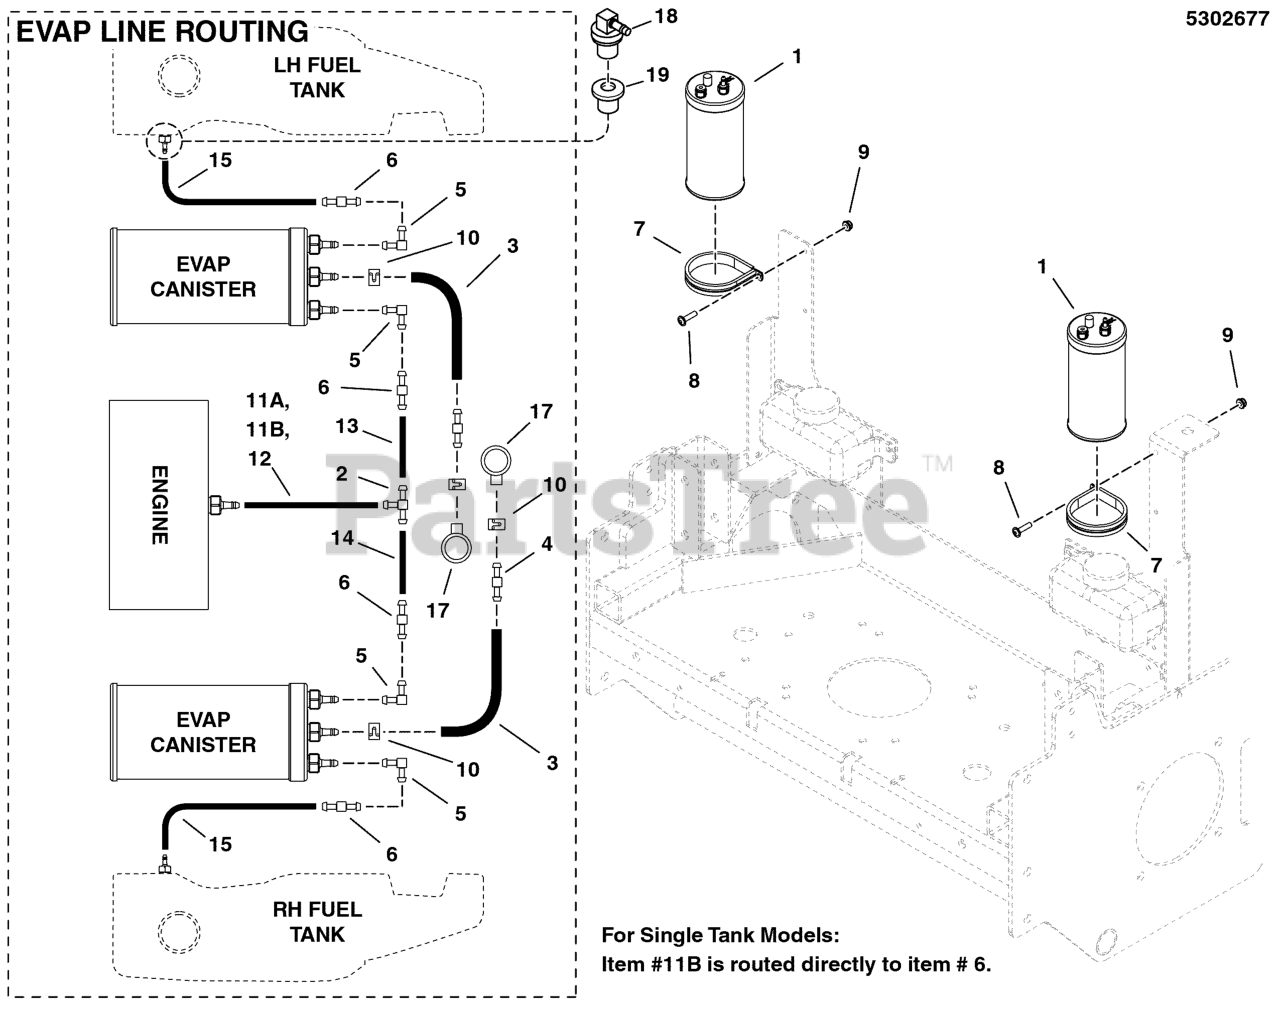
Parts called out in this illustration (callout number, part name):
1	CNSTR, CARB, 6 GAL
2	FITTING, 3/16" TEE, BARB TYPE, HDPE
3	HOSE, FORMED, EVAP CANISTER
4	FITTING, STRAIGHT, 10MMX10MM, PLASTIC
5	FITTING, 90 DEG, 3/16X3/16, SANTOPRENE
6	FITTING, STRAIGHT, 3/16X3/16, PLASTIC
7	CLAMP, 3" ID, CUSHIONED, STAINLESS
9	NUT, 1/4-20 HEX NYLOCK FLANGE
10	CLAMP, HOSE
12	HOSE, VAPOR, 5MM ID, 32.00 LG
13	HOSE, VAPOR, 5MM ID, 29.00 LG
13	HOSE, VAPOR, 5MM ID, 4.00 LG
14	HOSE, VAPOR, 5MM ID, 40.00 LG
14	HOSE, VAPOR, 5MM ID, 48.00 LG
15	HOSE, VAPOR, 5MM ID, 8.00 LG
16	DECAL, EPA CERTIFICATION
17	DUST FILTER, CANISTER (SV)
18	REMOTE VENT ASSEMBLY
19	GROMMET
